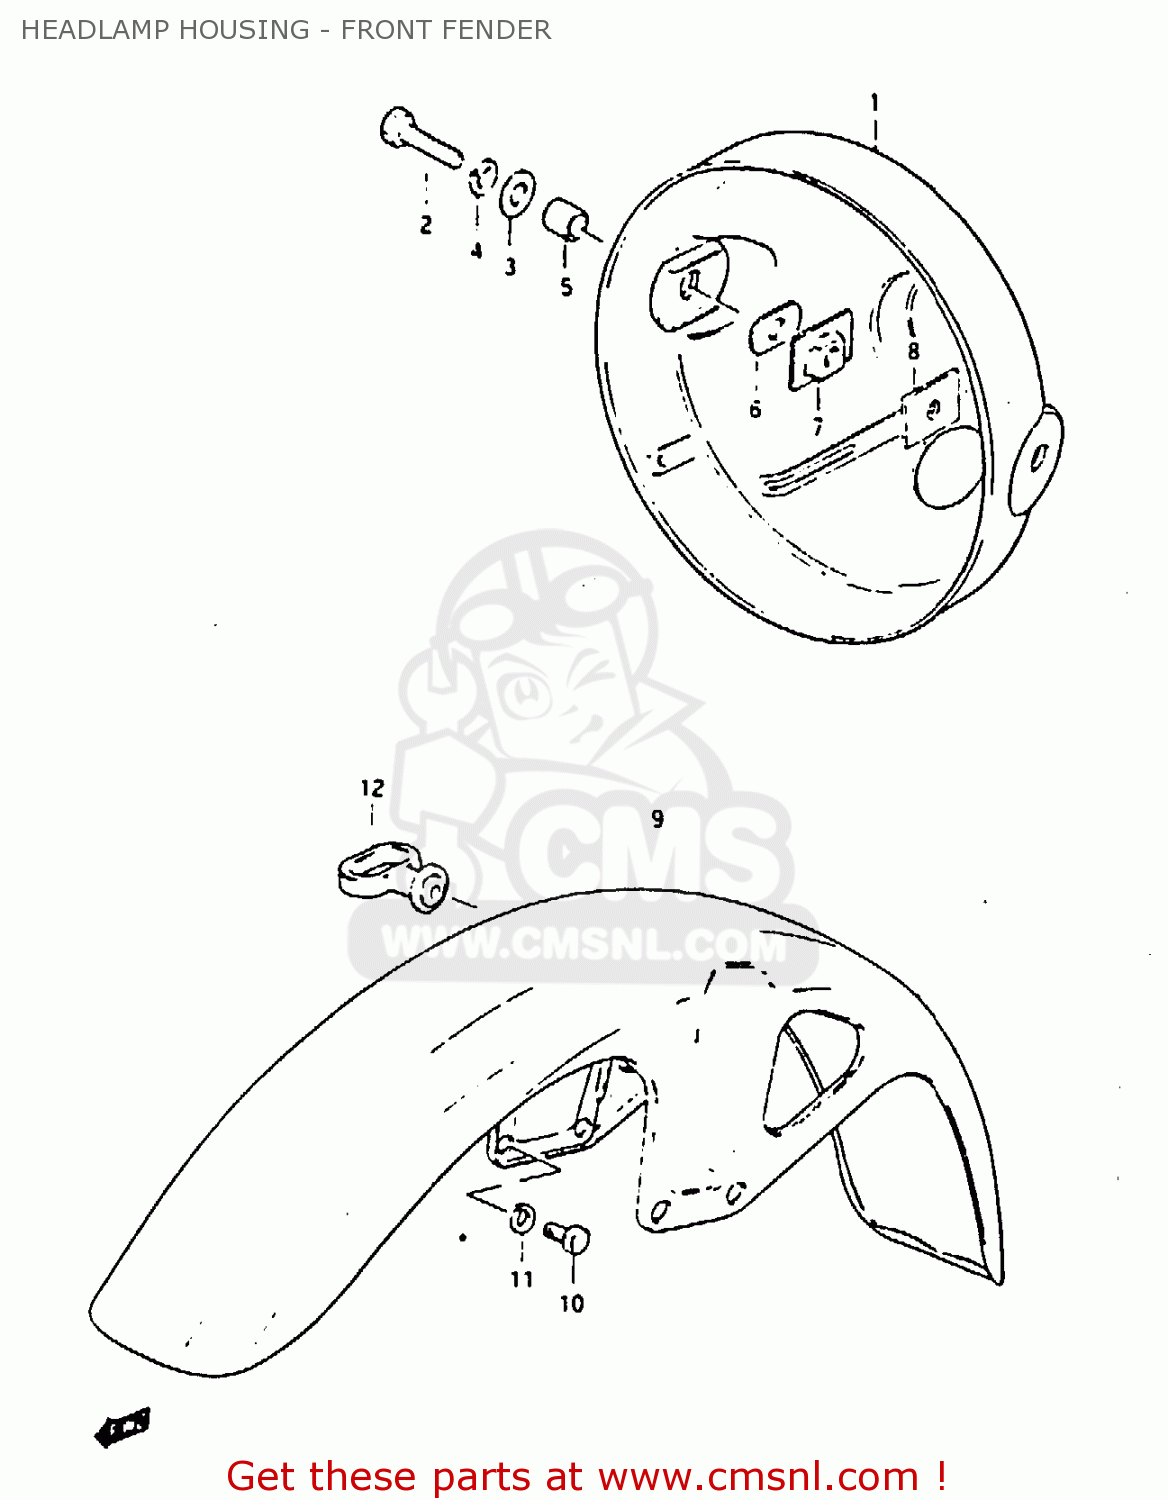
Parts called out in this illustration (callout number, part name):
1	HOUSING,HEADLAMP
2	BOLT
3	WASHER
4	LOCK WASHER
5	SPACER (8.8X12X7)
6	CUSHION
7	PLATE,HEADLAMP HOUSING
8	PLATE,HEADLAMP HOUSING
9	FENDER,FR
10	BOLT,8X16
11	LOCK WASHER
12	GUIDE,CABLE
